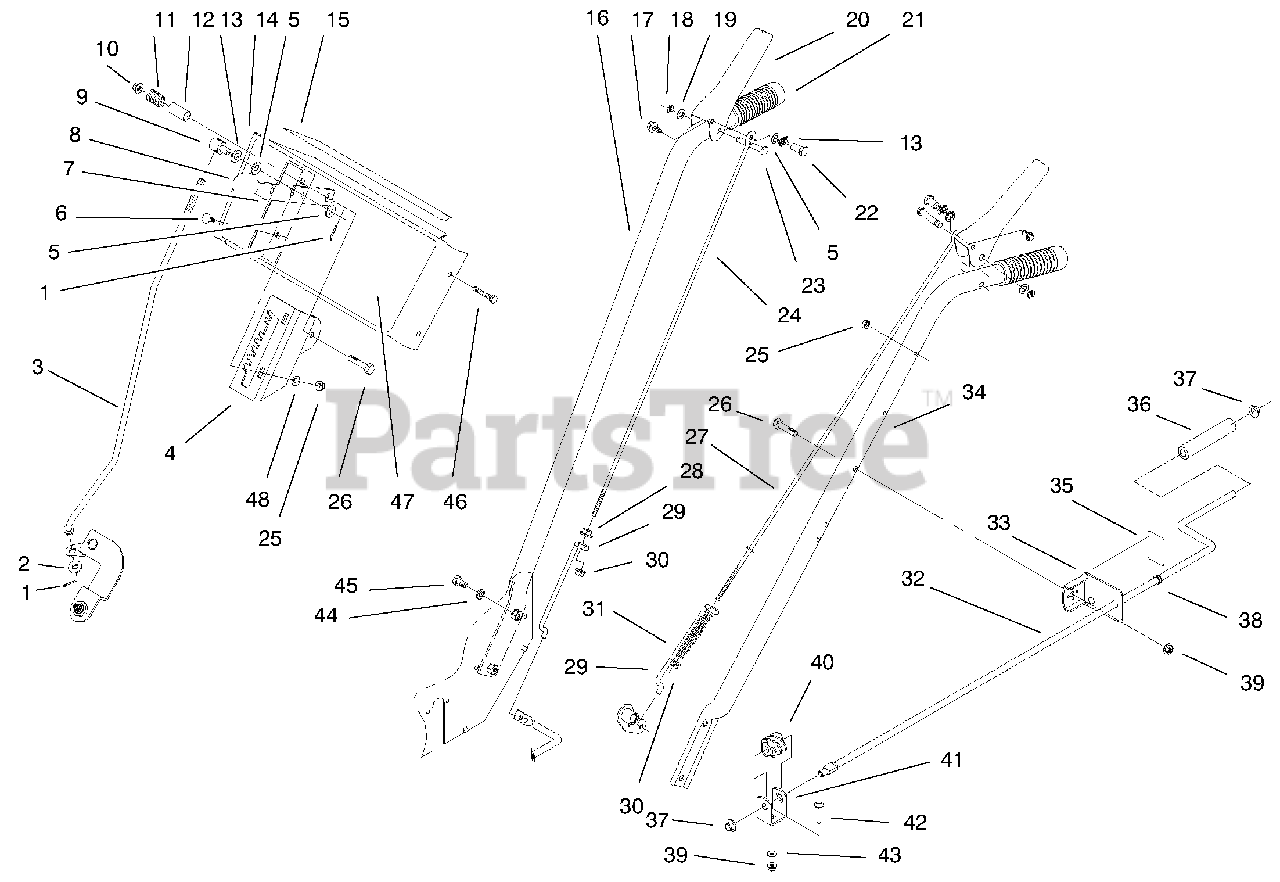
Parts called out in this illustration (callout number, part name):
1	Cotter-Pin
2	Washer-Flat
3	Rod-Shift
4	Mount-Speed Selector
5	Washer-Flat
6	Screw-CARR
7	Selector-Speed
9	Trunnion
10	Nut-Hex Flange
13	Washer-Spring
14	Panel-Control Asm
15	Decal-Escutcheon Back
16	Handle-Right
17	Screw-HHF
18	Klip Ring
19	Washer-Flat
20	Control Handle
21	Grip Handle
22	Post,Linkage Mounting
23	Control Lever Pin
24	Rod-Upper Engage Auger
25	Nut-Lock
26	Screw-HH
27	Rod-Upper Traction
28	Nut-Hex Flange
29	Rod-Lower Traction
30	Nut-Hex, Flange
31	Comp Spring
32	Rod Chute Control
33	Chute Rod Brkt
34	Left Handle (Black)
35	Decal-Chute Direction
36	Chute Control Grip
37	Retainer-Push On
38	Bushing-Sfl
39	Nut-Lock
40	Worm Gear Chute
41	Worm Bracket
42	Bolt S.n.
43	Pyrmd Lockwasher
44	Washer-belleville
45	Screw-HWH
46	Screw-HH
47	Decal Control Panel
